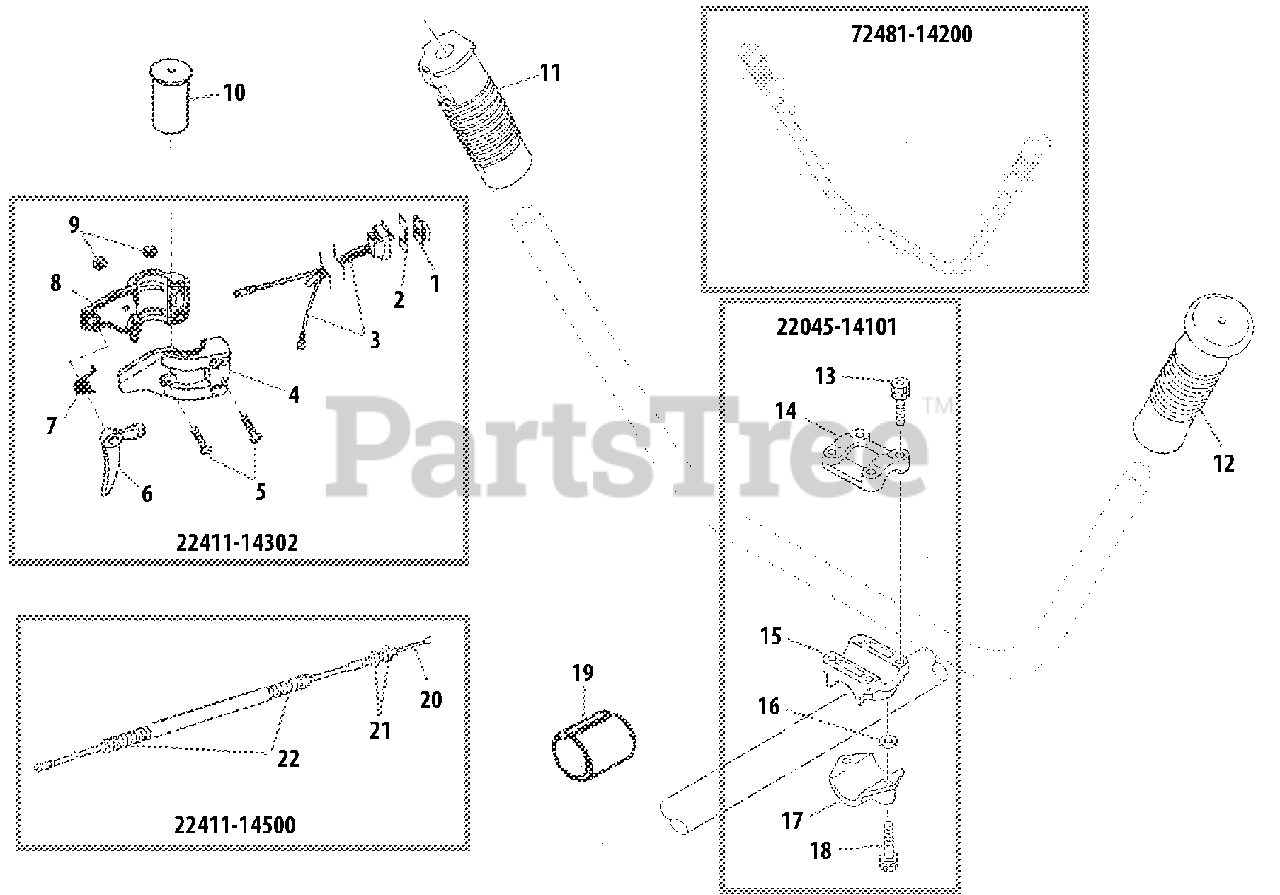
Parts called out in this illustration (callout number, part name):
1	KNOB
2	PLATE, SWITCH
3	IGNITION SWITCH ASSY
4	BRACKET - LEFT
5	SCREW - 5X20
6	TRIGGER, THROTTLE
7	SPRING, TRIGGER
8	BRACKET - RIGHT
9	NUT - 5
10	SPACER
11	GRIP, HANDLE - RIGHT
12	GRIP - LEFT
13	SCREW - 5X25
14	CLAMP - UPPER
15	BRACKET
16	WASHER - 5
17	CLAMP - LOWER
18	SCREW - 5X25
19	SPACER
20	CABLE, THROTTLE
21	NUT - 6
22045-14101	HANDLE BRACKET KIT
22411-14302	THROTTLE CONTROL KIT
22411-14500	THROTTLE CABLE ASSY
72481-14200	HANDLE ASSY
